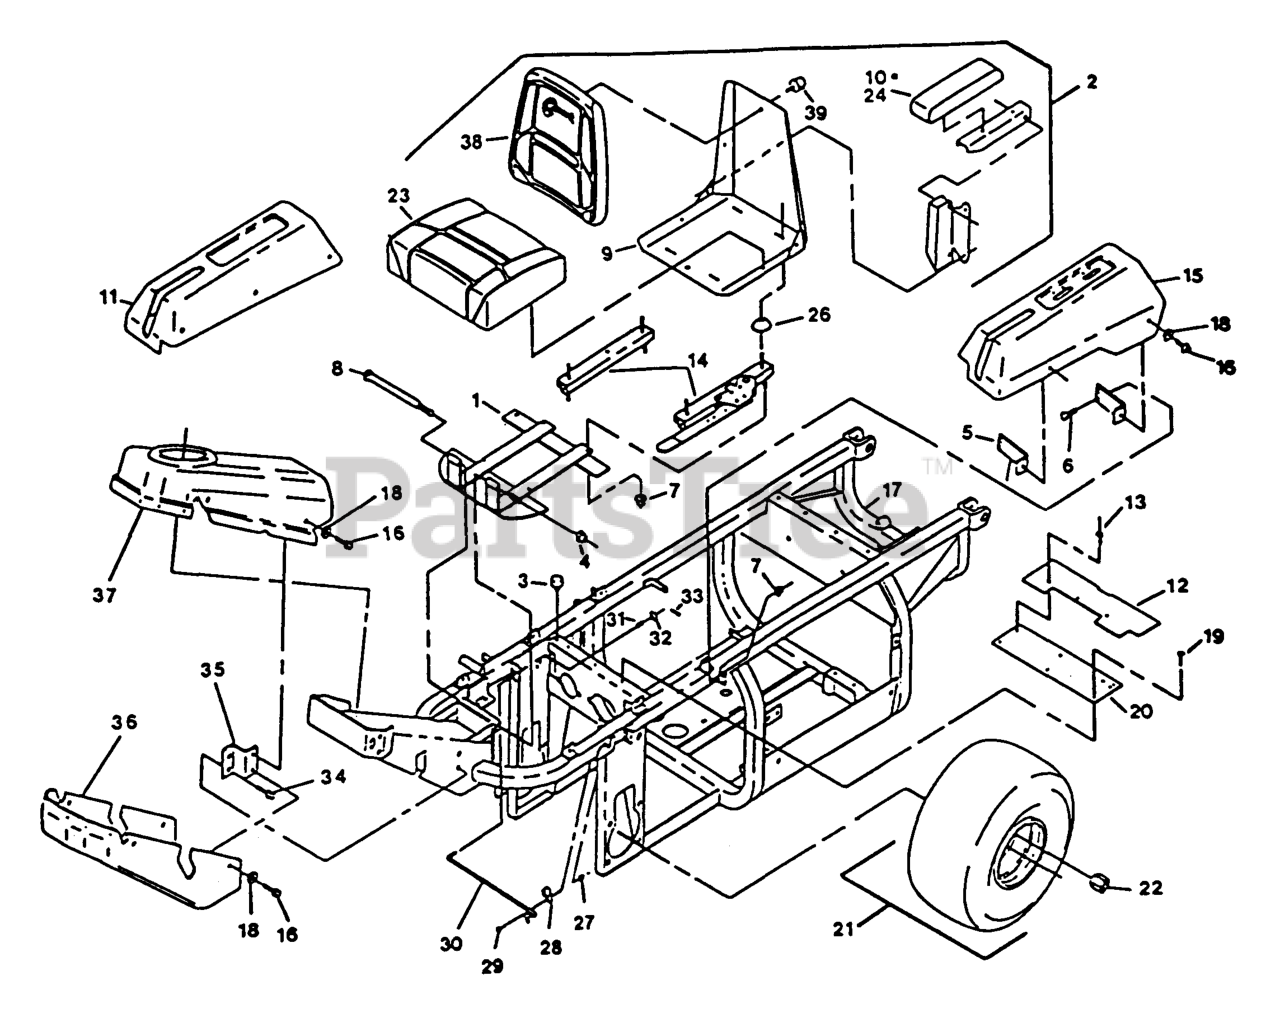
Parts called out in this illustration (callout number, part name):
11	FENDER,RH RANGER
12	SHIELD,PUMP
13	RIVET-POP
15	FENDER,LH RANGER
20	SHIELD,PUMP BELT
21	WHEEL AND TIRE ASM
26	SPACER-TRACK
28	CLIP,SEAT HOLDUP ROD
30	ROD,SEAT HOLDUP
31	SPRNG,ST HOLDUP ROD
36	CONSOLE,STEERING BOTTOM
37	CONSOLE,STEERING TOP
